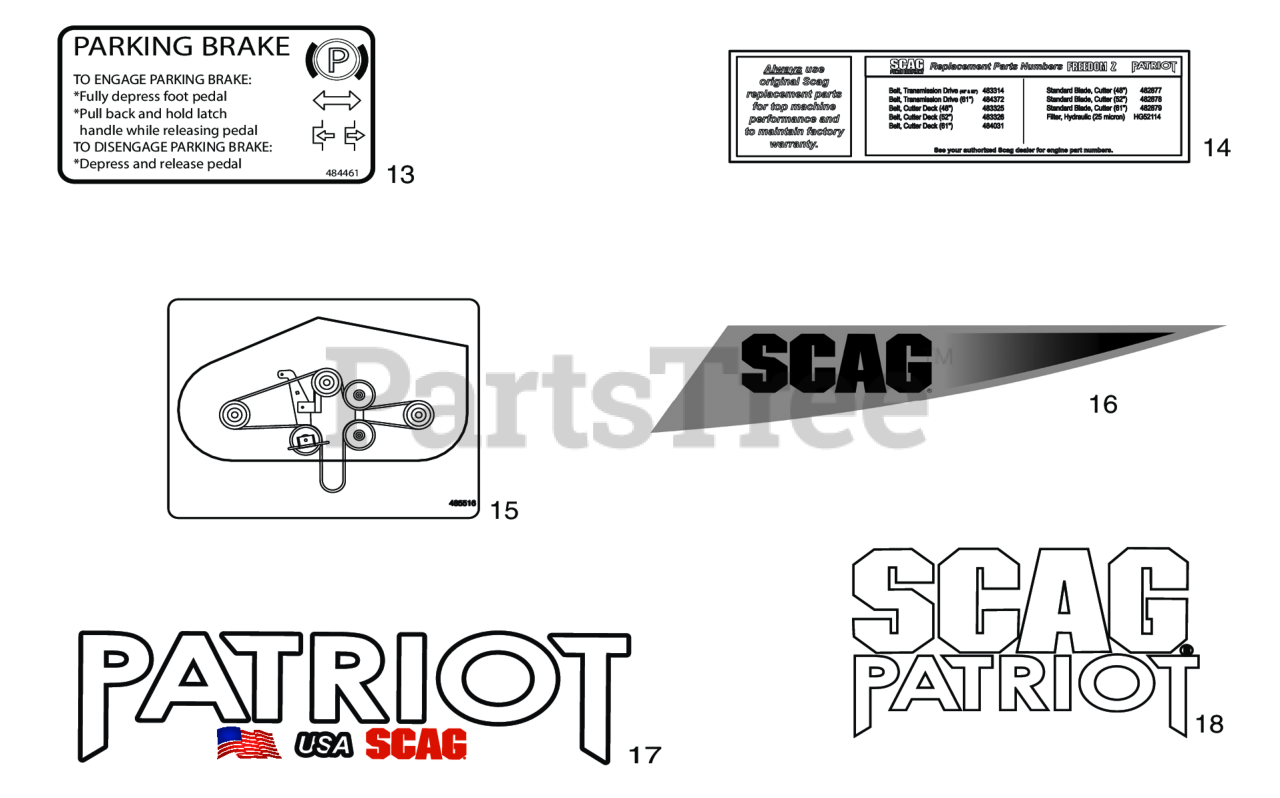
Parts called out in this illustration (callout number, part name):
13	Decal, Brake
14	Decal, SFZ / SPZ Replacement Parts
15	Decal, SZL / SFZ / SPZ Belt Routing
16	Decal, Scag - Fuel Tank
17	Decal, Patriot, (Scag Gold Logo) - Fuel Tank
18	Decal, Scag Patriot, (Scag Gold Logo) - Fuel Tank
